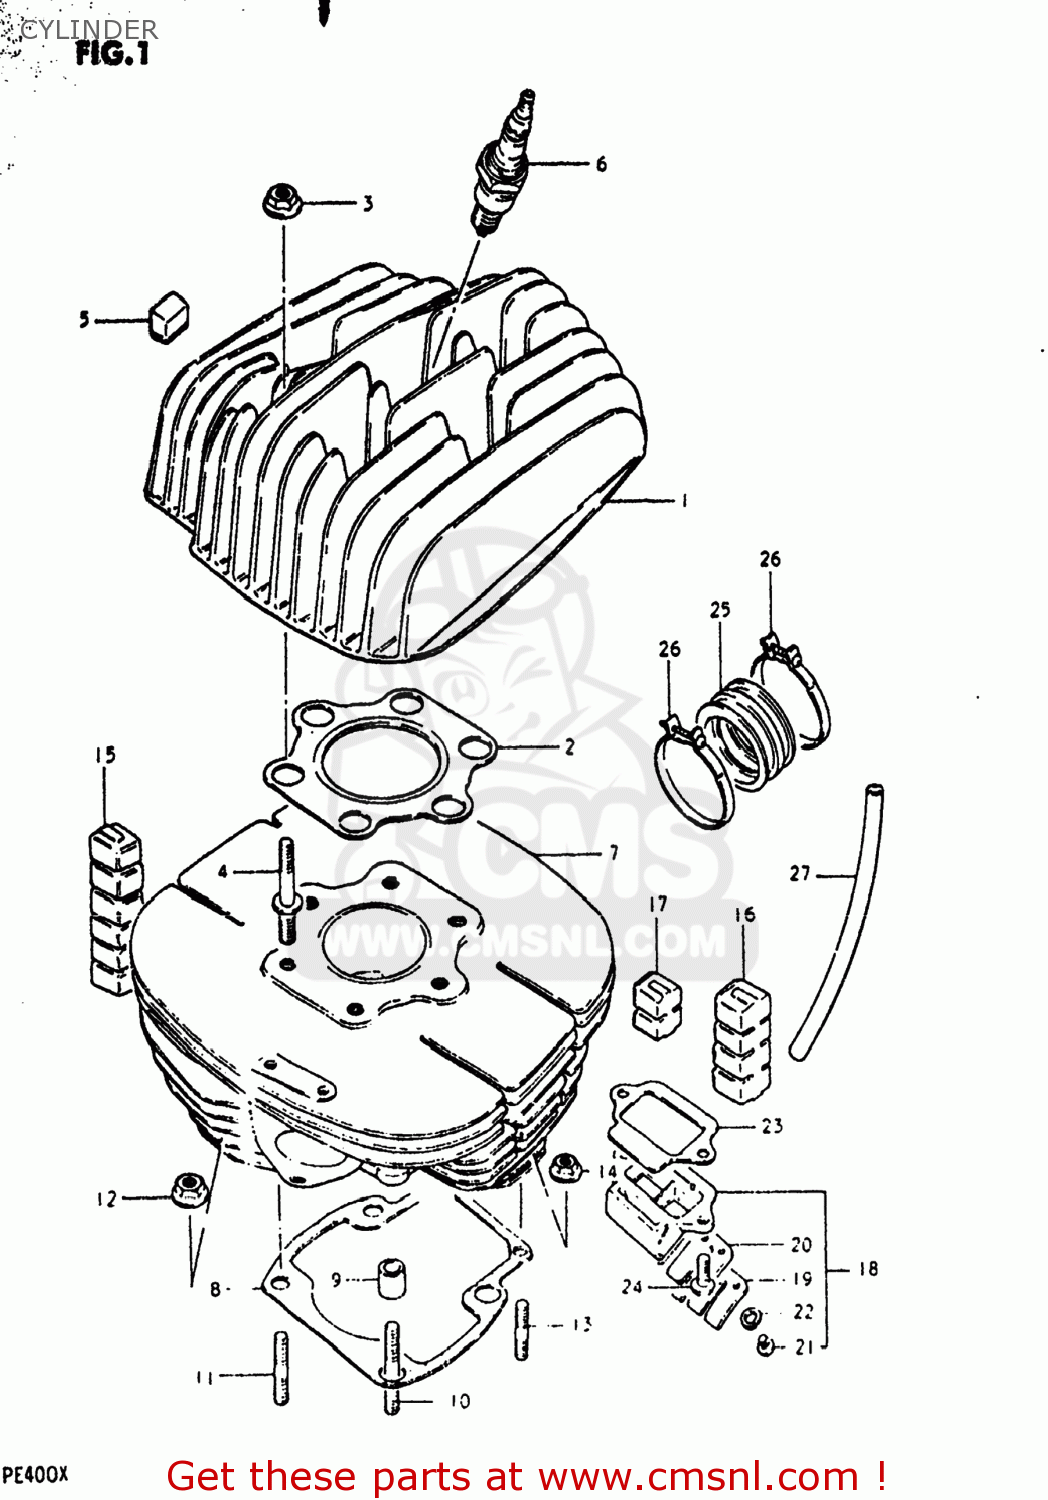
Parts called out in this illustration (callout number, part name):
1	HEAD,CYLINDER
2	GASKET,CYLINDER HEAD (NAS)
3	NUT
4	BOLT,STUD
5	PAD,CYLINDER HEAD
6	SPARK PLUG N-2G CHMP
7	CYLINDER
8	GASKET,CYLINDER (MCA)
9	PIN
10	STUD BOLT (L:40)
11	STUD 10X25
12	NUT
13	STUD 6X20
14	NUT
15	PAD,CYLINDER
16	PAD,CYLINDER
17	PAD,CYLINDER
18	VALVE ASSEMBLY,REED
19	STOPPER,REED VALVE
20	VALVE,REED
21	SCREW
22	LOCK WASHER
23	GASKET,REED VALVE (MCA)
24	SCREW
25	PIPE,INTAKE
26	CLAMP
27	HOSE
